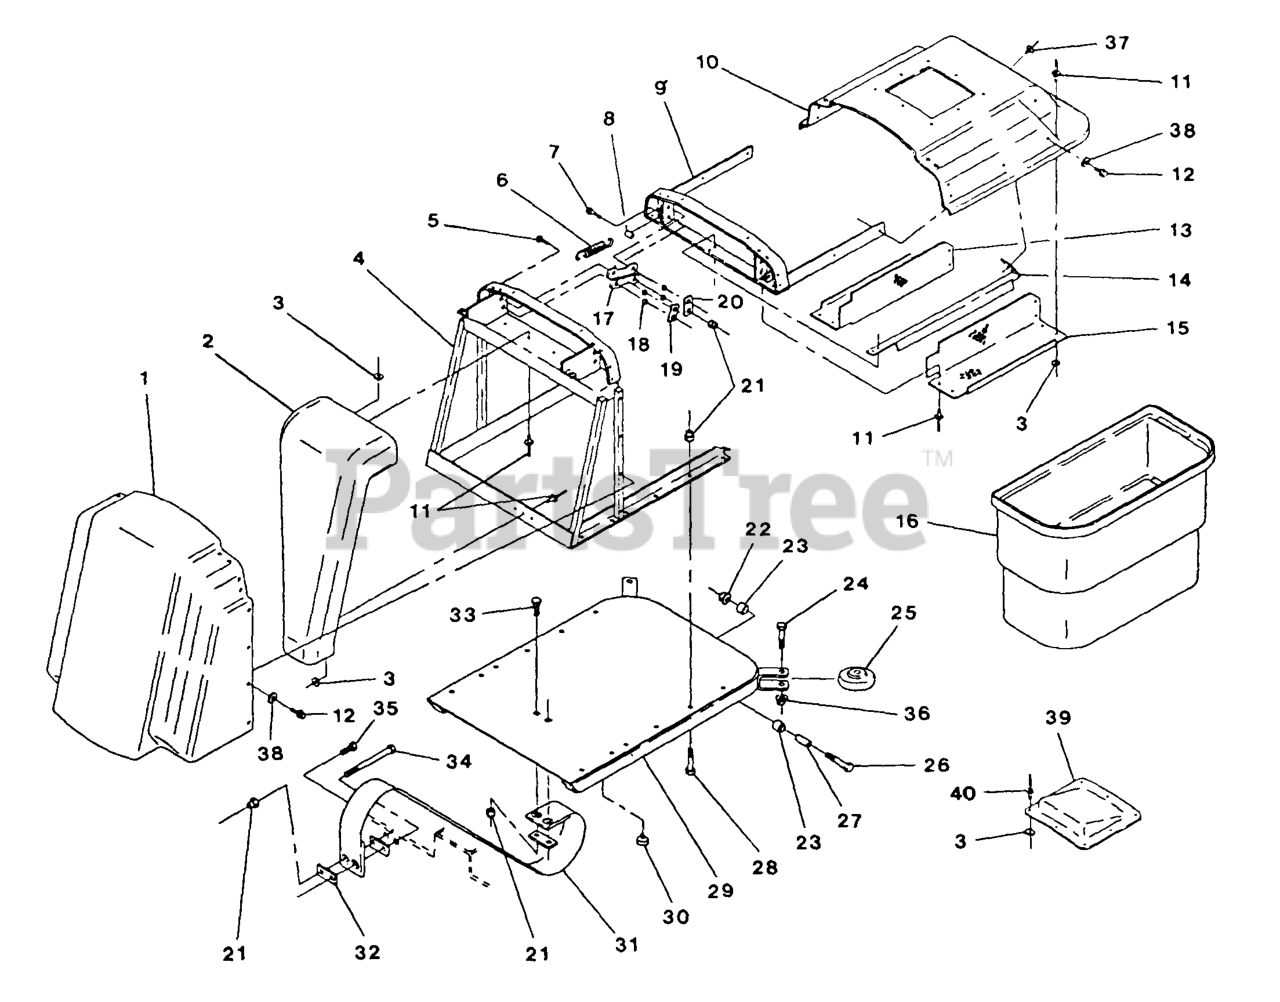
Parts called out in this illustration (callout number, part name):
6	SPRING,CATCHER LID
8	BUSHING,LID SPRING
10	TOP,GRASS CATCHER
13	SCREEN,PERFORATED RH PNT
15	SCREEN,PERFORATED LH PNT
17	LINK,HINGE PLTD
23	SLEEVE-BEARING
25	WHEEL,RUBBER
27	BUSHING,BOX PIVOT
31	STRAP,BOX RESTRAINT
32	CLAMP,STRAP
33	Bolt, Carriage 1/4-20 X 1
37	Pop Rivet, Steel 3/16 X .250
39	WINDOW,GRASS CATCHER
